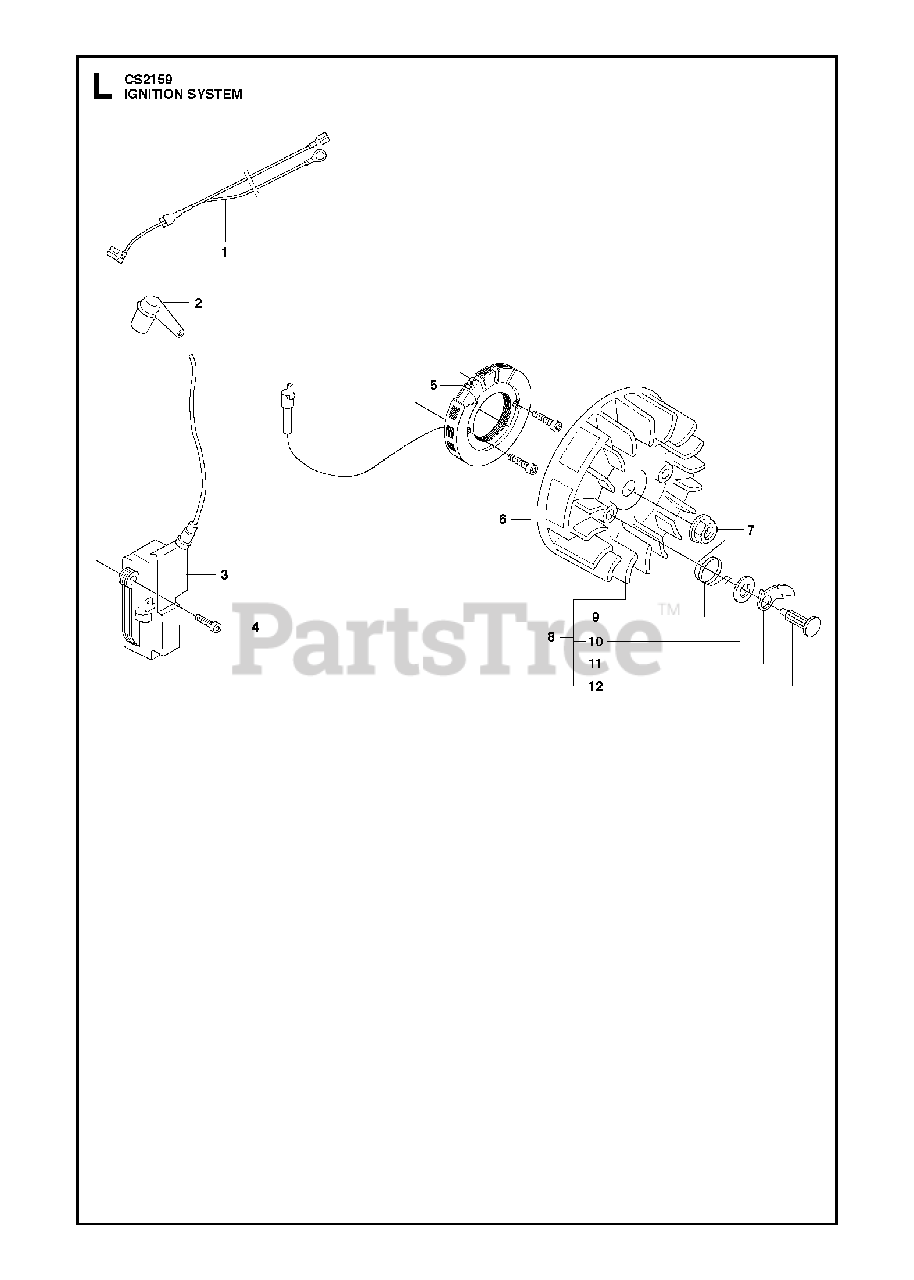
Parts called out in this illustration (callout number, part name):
1	WIRING ASSY
2	SPARK PLUG CONN. KIT
3	IGNITION MODULE
5	GENERATOR
7	NUT W/ WASHER
8	FLYWHEEL
9	SPRING
10	WASHER
11	PAWL
12	PIN, STARTER CATCH
